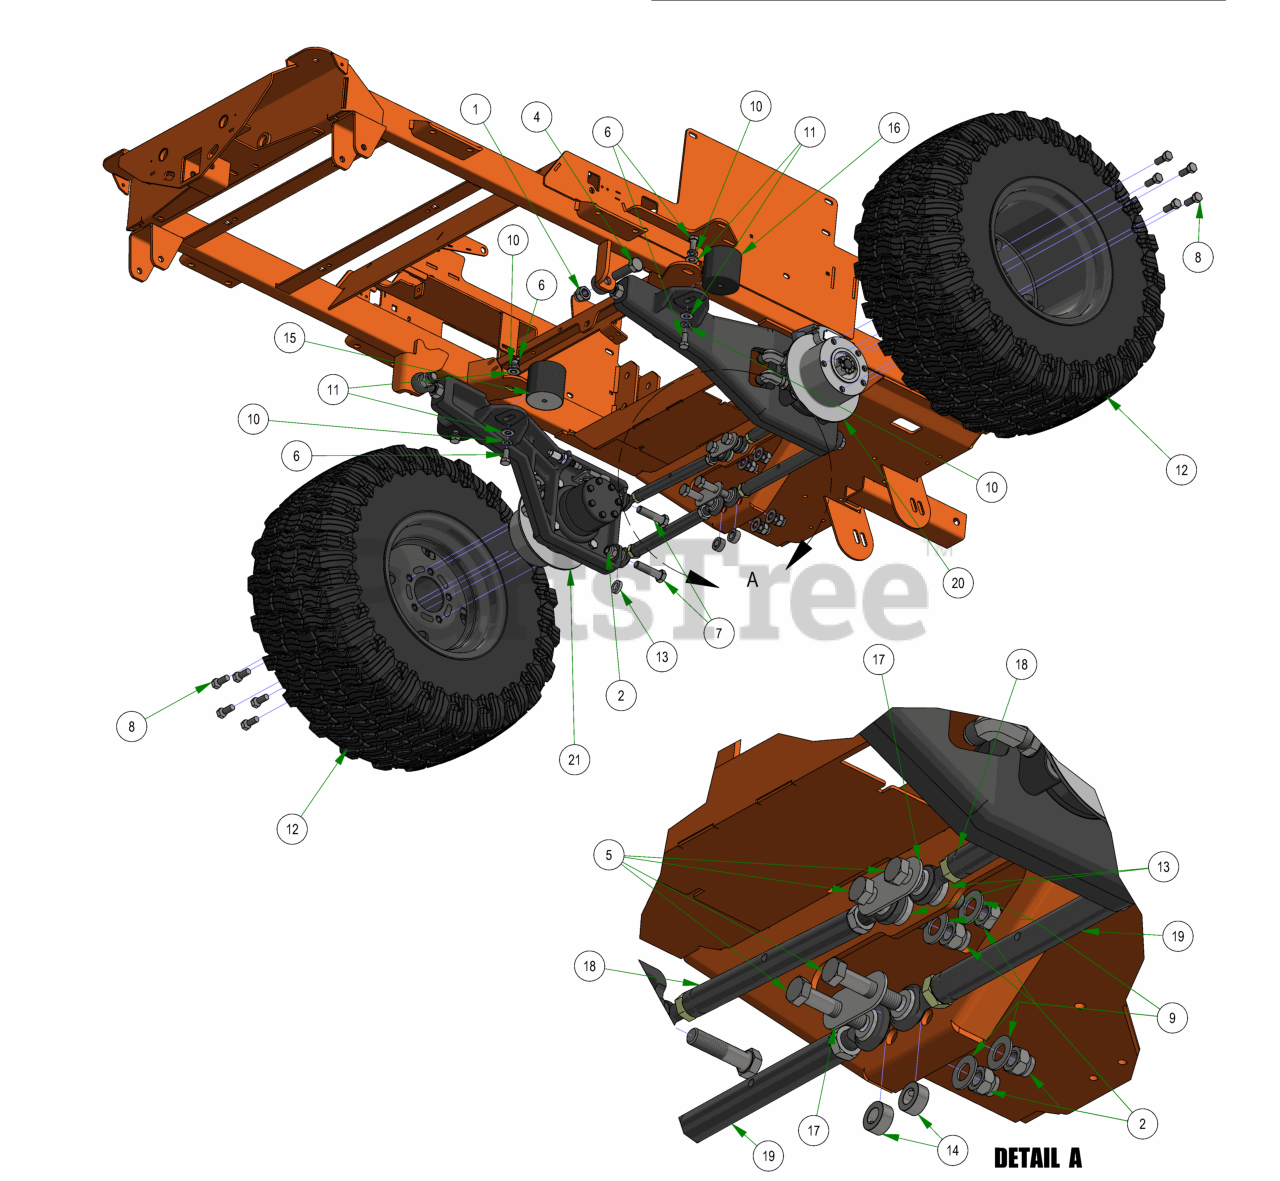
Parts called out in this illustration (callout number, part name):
1	3/4-10 NYLON INSERT LOCKNUT ZINC
2	5/8-11 NYLON INSERT LOCKNUT ZINC
3	2019 2" x .25 Rubber Grommet
4	3/4-10 X 2-1/2 HEX CAP SCREW (GR.5) ZINC
5	5/8-11 X 2-3/4 HEX CAP SCREW (GR.5) ZINC
6	1/2-13 X 1 HEX CAP SCREW (GR.5) ZINC
7	5/8-11 X 2-1/2 HEX CAP SCREW (GR.5) ZINC
8	1/2-20 x 60° Lug Bolts Zinc Grade 8
9	5/8" Flat Washer SAE Spec Grade 8
10	1/2 SPLIT LOCKWASHER (GR.8) ZINC/YELLOW
11	1/2 SAE FLAT WASHER (1-1/16" OD) GR.8 ZINC YELLOW
12	2019 Assy-26x12-12 Reaper Turf -10.5" Rim
13	Spacer 1.125OD x .625 ID x .250 Length
14	5/8 SOLID SHAFT COLLAR (W/1 SET SCREW) ZINC
15	Vibration Mount-Blue Dot
16	Vibration Mount-Green Dot
17	2019 Suspension Gusset Outlaw
18	2019 Suspension Radius Rod Assembly
19	2019 Suspension Radius Rod Assembly
20	2019 Renegade Trailing LH Arm Assy
21	2019 Renegade Trailing RH Arm Assy
22	2019 Renegade Gas Frame - Powdercoated
